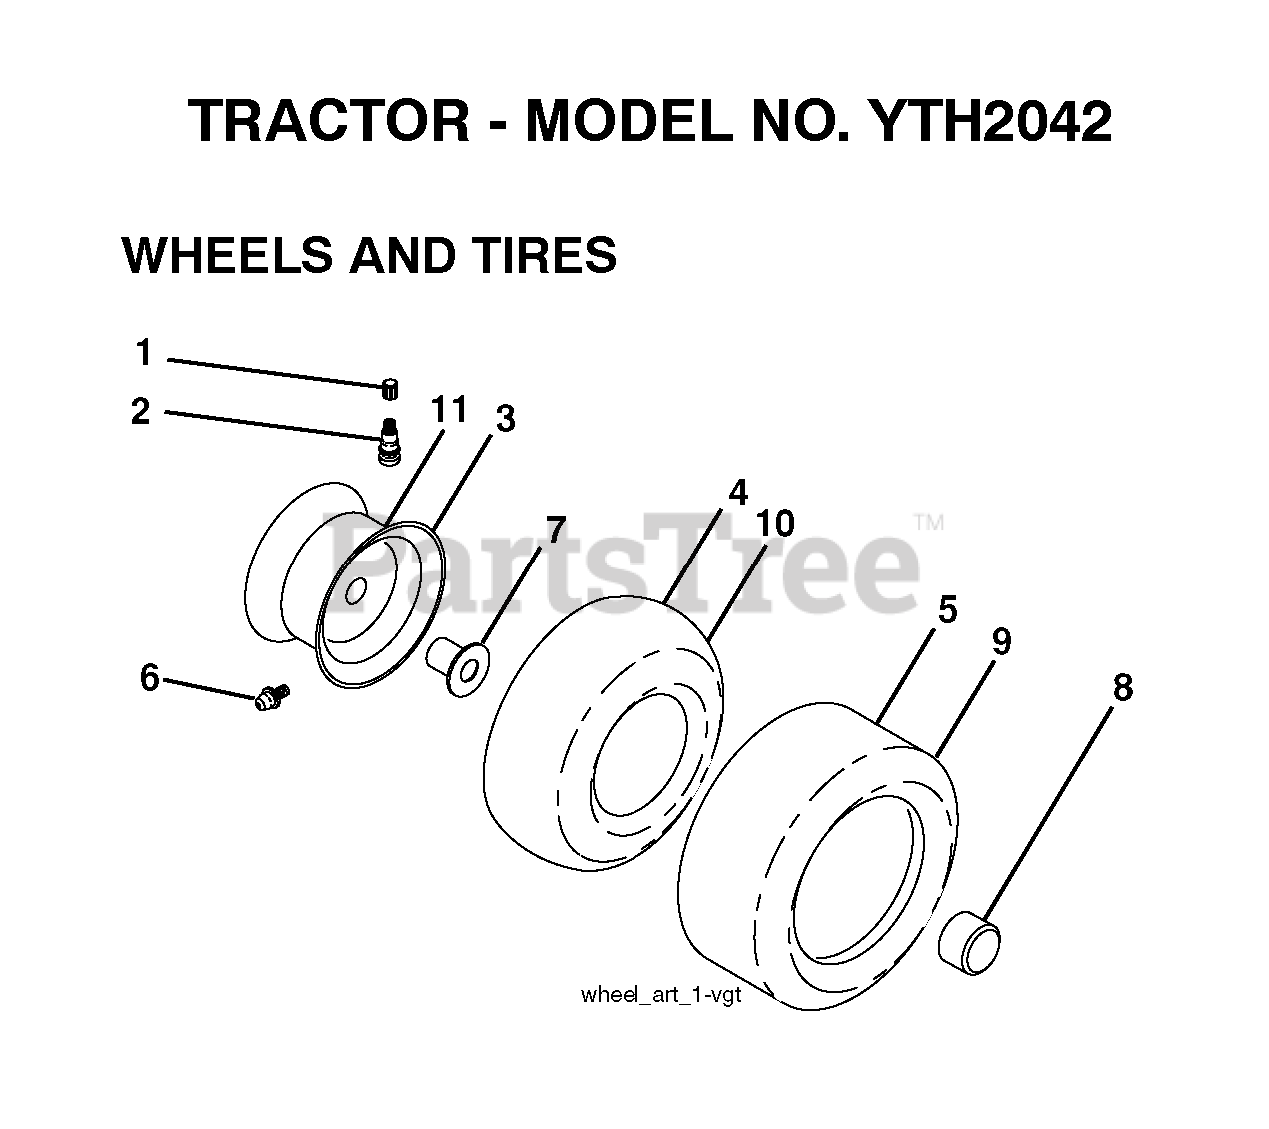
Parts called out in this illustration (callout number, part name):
2	VALVE STEM LT
3	RIM ASM 6" FRONT SILVER
4	TUBE.5.3/4.5/6
5	TIRE HEAVY DUTY
6	FITTING LT
7	BEARING T
8	CAP, AXLE BLK
9	TIRE HEAVY DUTY
10	TUBE
11	RIM ASM 8" REAR SILVER
